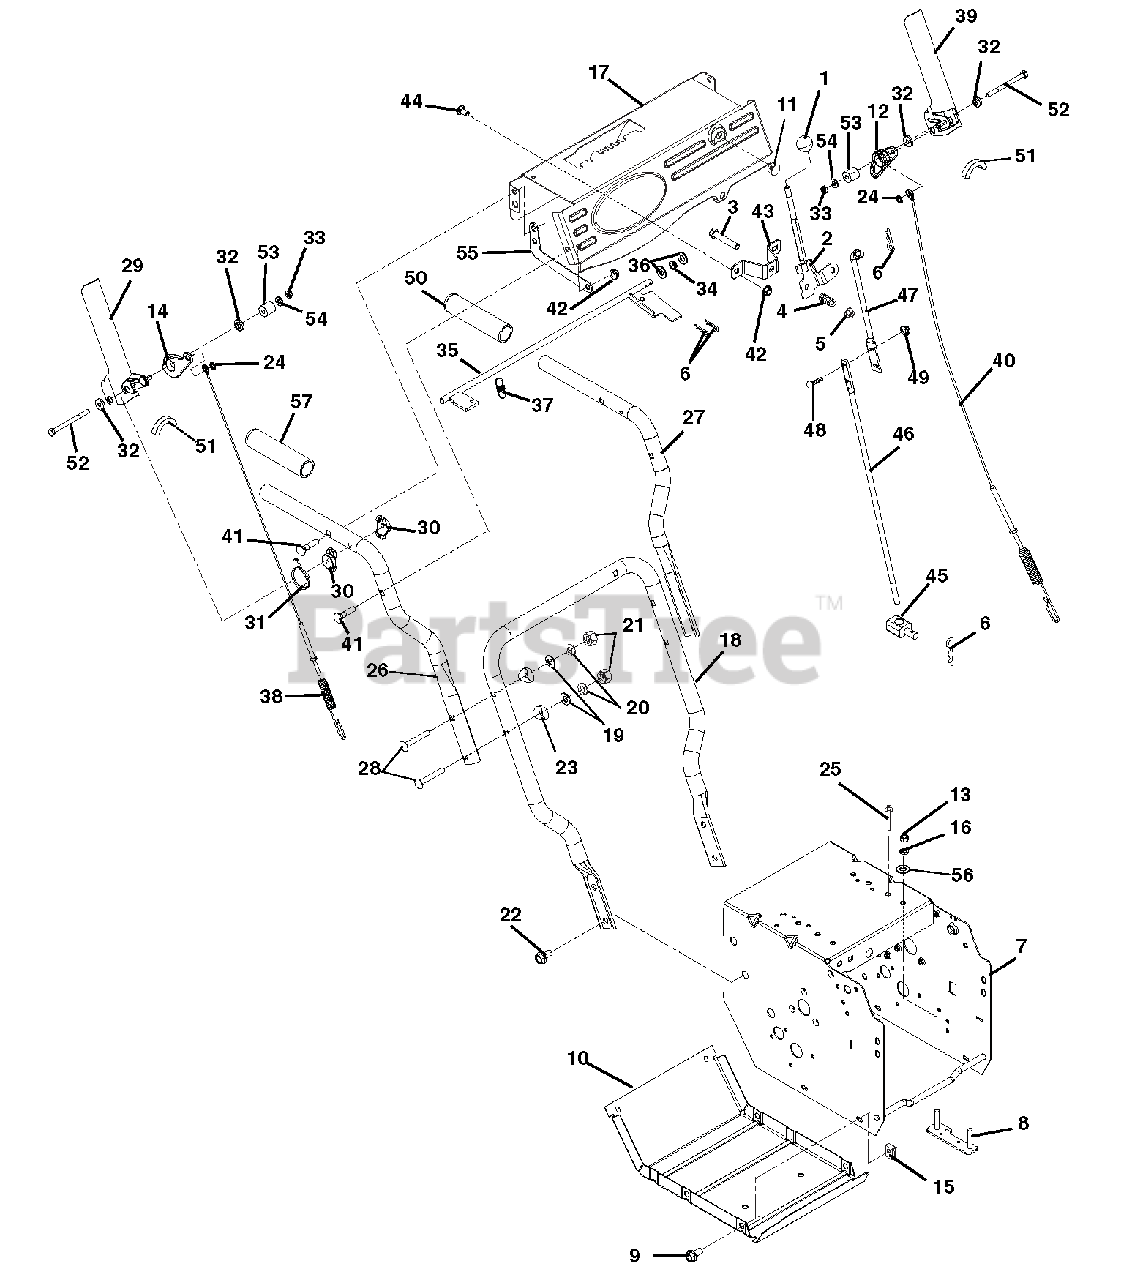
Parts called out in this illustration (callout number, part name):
1	KNOB,BALL -BLACK 1.47" .375-16
2	WMT, SHIFT LEVER
3	@BLT-HEX .38-16X2.00 GR5 YWZC
4	SG-COMP .125X.781X1.250
5	@NUT-LK-TOP-FLG .38-16 YWZC
6	PIN-HAIR INT .08X.18X1.18 YWZC
7	FRAME, 920/921
8	STRAP, ENGINE BOLT-WELDMENT
9	BLT-HEX .25-20X.75 HWH YZ GR5
10	COVER, BOTTOM
11	HOLE PLUG, PLASTIC .44 HOLE
12	CAM, INTERLOCK - LH
13	@NUT-HEX .31-18 YWZC
14	CAM, INTERLOCK - RH
15	NUT-RTNR .25-20X.56
16	WSHR-LK .312X.097 HVY YWZC
17	CONTROL PANEL W/DECAL
18	HANDLEBAR, LOWER (COMPACT)
19	@WSHR-FL-STL.38X.875X.083 YWZC
20	WSHR-LK .312X.097 HVY YWZC
21	@NUT-LK-NYL .312-18 YWZC
22	BLT-SERHFWH .38-16X.75 YWZC
23	SPACER, HANDLEBAR
24	RG-RTNG-EXT .250X.010
25	RVT-POP .187 YZ
26	HANDLEBAR, UPPER - RH COMP/DEL
27	HANDLEBAR, UPPER - LH COMP/DEL
28	@BLT-RDHDSQNK .31-18X2.25 G5YZ
29	PADDLE, CLUTCH - RH COMPACT
30	SPACER, HANDLEBAR
31	SPRING, TORSION
32	BSHG, FLG .266X.42X.150 PM
33	NUT-JAM-NYL .250-20 W/INSERTYZ
34	BUSHING, POLYLINER-.38 SNAPIN
35	WELDMENT, INTERLOCK SHAFT
36	@WSHR-FL-STL.406X.812X.065 YWZ
37	SPRING, EXTENSION
38	CABLE, ATTACHMENT, COMPACT
39	PADDLE, CLUTCH - LH COMPACT
40	CABLE, TRACTION - COMPACT
41	BLT-RDHDXLSQNK .31-18X1.5 G5YZ
42	@NUT-LK-TOP-FLG .31-18 YWZC
43	BRKT, SHIFT MOUNT
44	@BLT-RHDSSQNK .31-18X.62 G5YZ
45	PIVOT,SHIFT ROD .375-16(TRUNN)
46	ROD, SHIFT - LOWER
47	ROD, SHIFT - UPPER
48	@BLT-RDHDSQNK .25-20X.75 G5YZ
49	@NUT-LK-TOP-FLG .25-20 YWZC
50	HANDLE GRIP
51	EDGING, CLUTCH PADDLE - 2.00"
52	@BLT-HEX .25-20X3.25 YWZC
53	BSHG, SLV .266 X .750 X .750
54	@WSHR-FL-STL.281X.62X.065 YWZC
55	STRAP, SUPPORT - DASH PANEL
56	@WSHR-FL-STL.344X.688X.065YWZC
57	HANDLE GRIP
